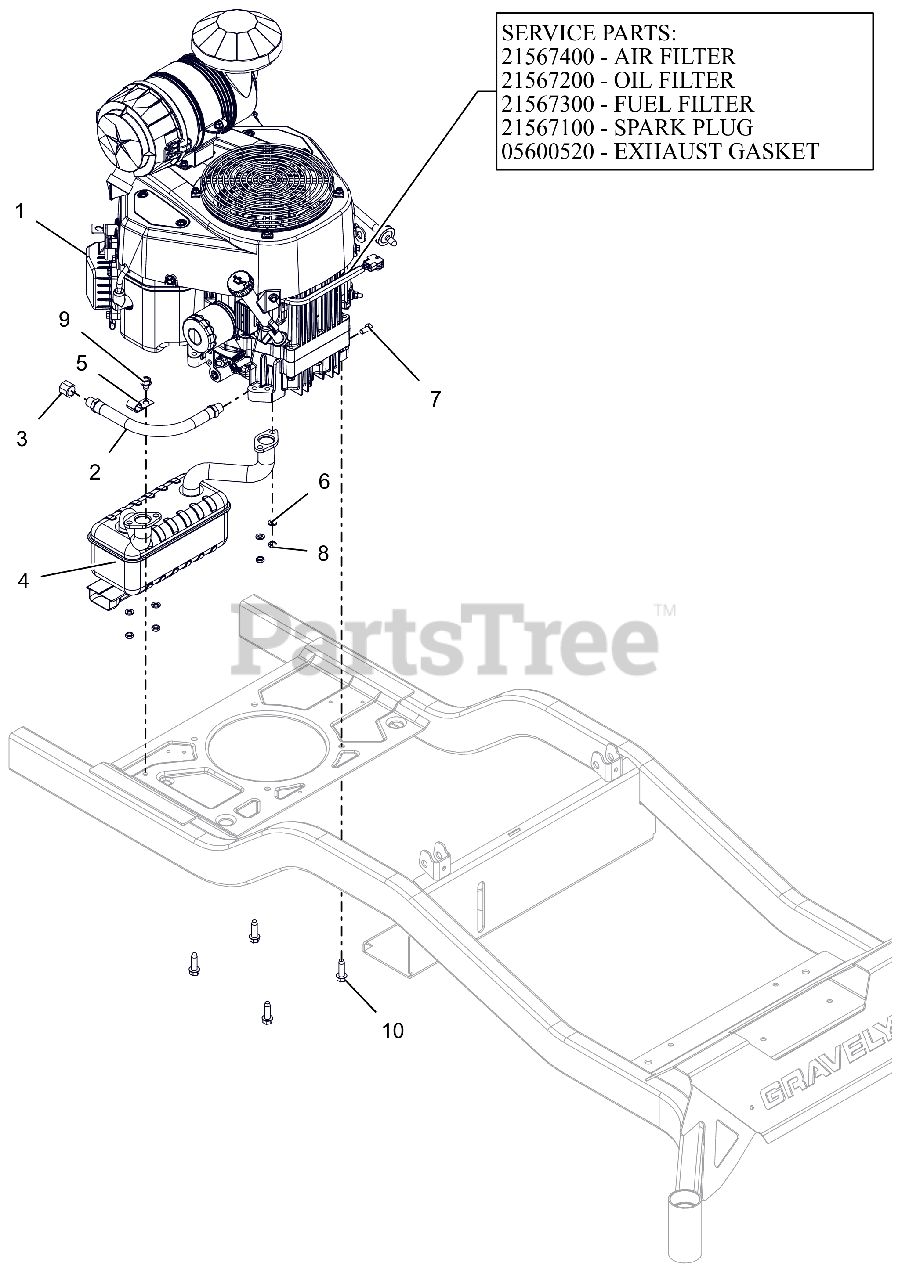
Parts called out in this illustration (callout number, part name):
1	ENGINE, LONCIN 764cc
1	FILTER, AIR
1	FILTER, OIL LONCIN
1	FILTER, FUEL
1	PLUG, SPARK
1	GASKET, MUFFLER LONCIN
2	HOSE,HYD .38-11-0K M6NO-M6N0
3	PIPE CAP 3/8 NPT FEMALE
4	MUFFLER,
6	WSHR,LK-REG .312X.078 ZCC
7	BLT, HEX .31-18X.625 G5 ZCC
8	NUT,NYL M8-1.25 G8.8 ZCC
9	SCR,TAP .375-16X.50 HWH TR ZCC
10	SCR,TAP .375-16X1.25HWH TR ZCC
